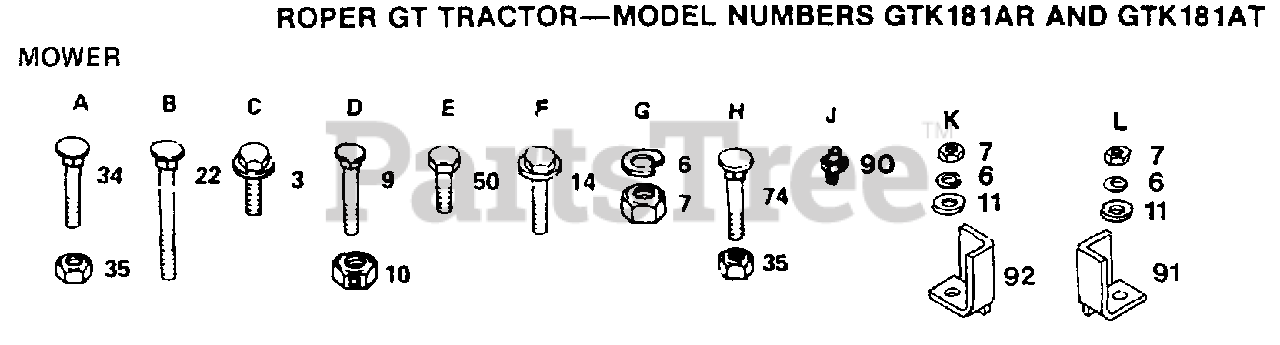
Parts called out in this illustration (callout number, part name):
3	SCREW LT
6	LOCKWASHER
7	NUT.HEX.5/16-18
9	BOLT
11	WASHER
14	SCREW
22	BOLT
34	BOLT
50	BOLT
74	BOLT
90	ZERK M
91	BRACKET RH M
92	BRACKET T
